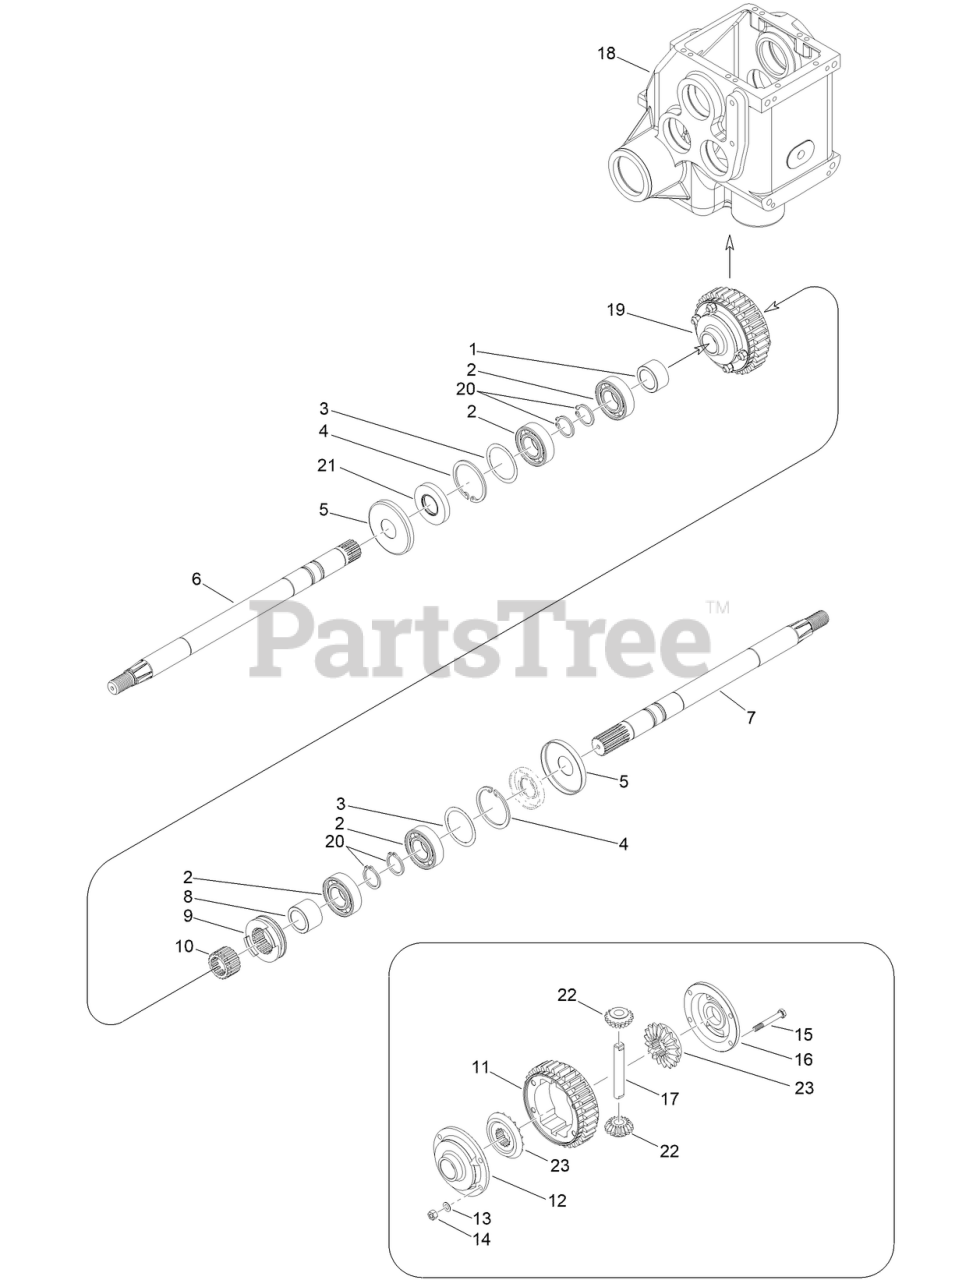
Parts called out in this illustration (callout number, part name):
1	SPACER, SHAFT
2	BEARING
3	SPACER
4	RING-RETAINING, INT
5	CAP, GEARBOX
6	DRIVESHAFT, LH
7	DRIVESHAFT, RH
8	SPACER
9	SLEEVE, DIFFERENTIAL LOCK
10	SPLINED BUSHING
11	SPUR GEAR, DIFFERENTIAL
12	COVER, LH DIFFERENTIAL GEAR
13	WASHER-WAVE
15	SCREW-HH
16	COVER, RH DIFFERENTIAL GEAR
17	PIN, SATELLITE
18	GEARBOX
19	DIFFERENTIAL GEAR, ASSEMBLY
20	RETAINER, SHAFT
21	SEAL, OIL
22	GEAR, SATELLITE
23	GEAR, PLANETARY
